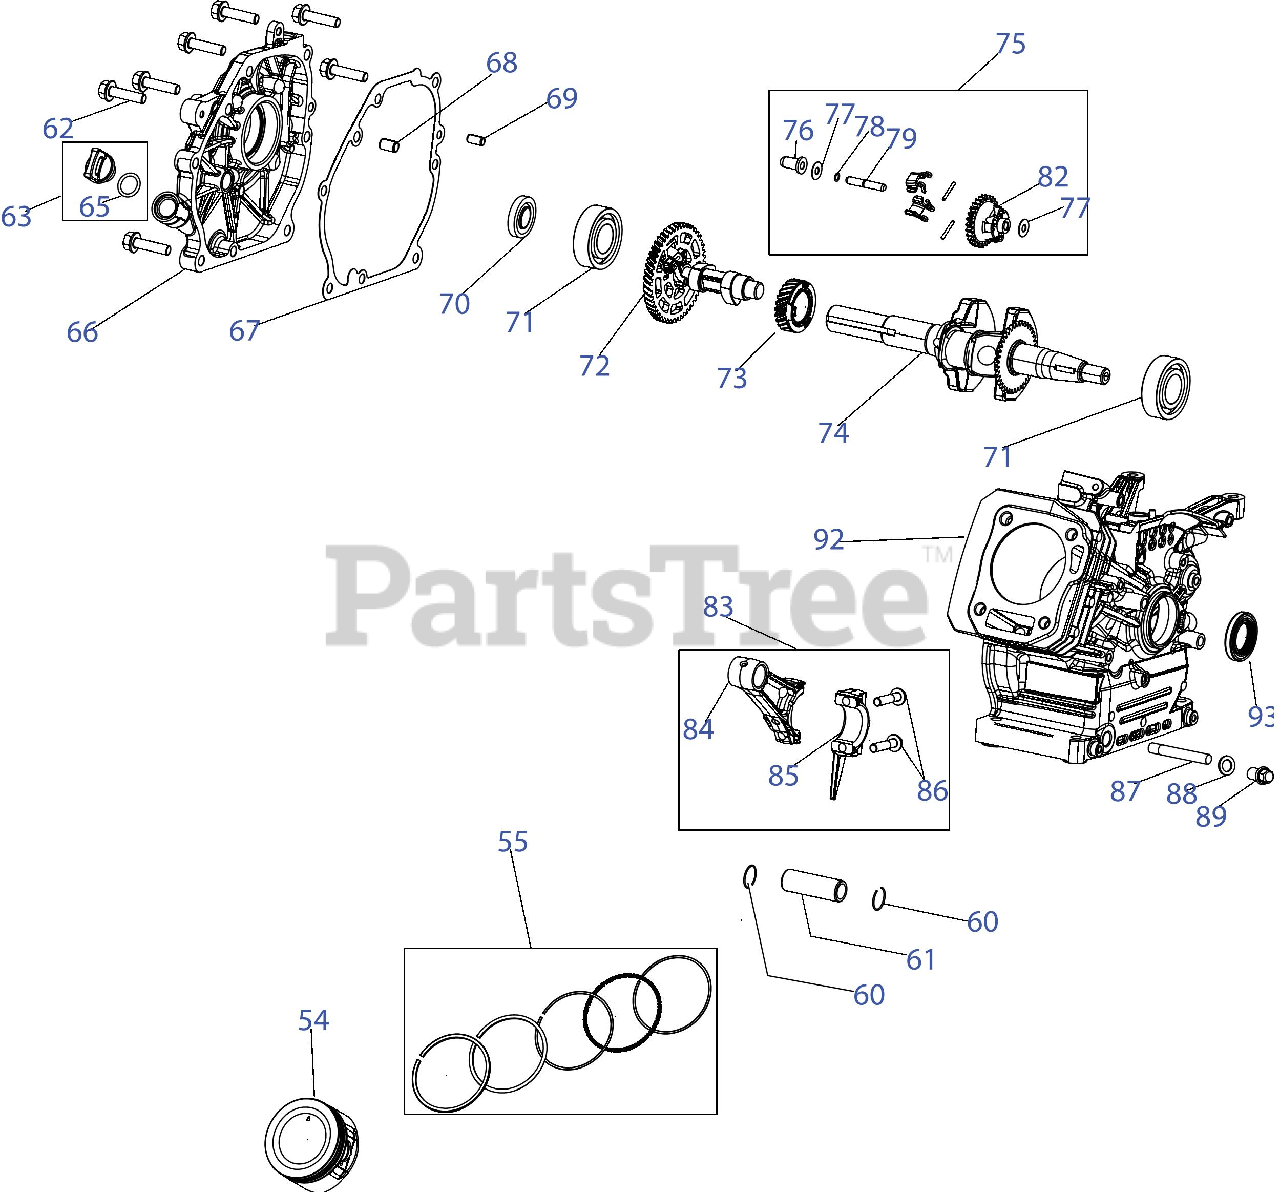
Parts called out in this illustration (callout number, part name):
55	Piston Ring Set
61	Piston Pin
62	Bolt, M6?32
65	O-Ring, 15.8?2.5
66	Crankcase Cover
67	Gasket, Crankcase
68	Pin, 9?14
69	Pin, 7?14
70	Oil Seal, 25?41.25?6
71	Bearing, 6205
73	Drive Timing Gear
74	Crankshaft
75	Governor Gear
76	Governor Cup
77	Washer, 6.2?0.6?15
78	Retaining Ring
79	Governor Shaft
82	Governor Gear
83	Connecting Rod Assembly
84	Connecting Rod
85	Connecting Rod Cap
86	Connecting Rod Bolt
87	Oil Drain Pipe
88	Washer, 10?1.5?16
89	Earth Bolt
93	Oil Seal, 25?41.25?6
